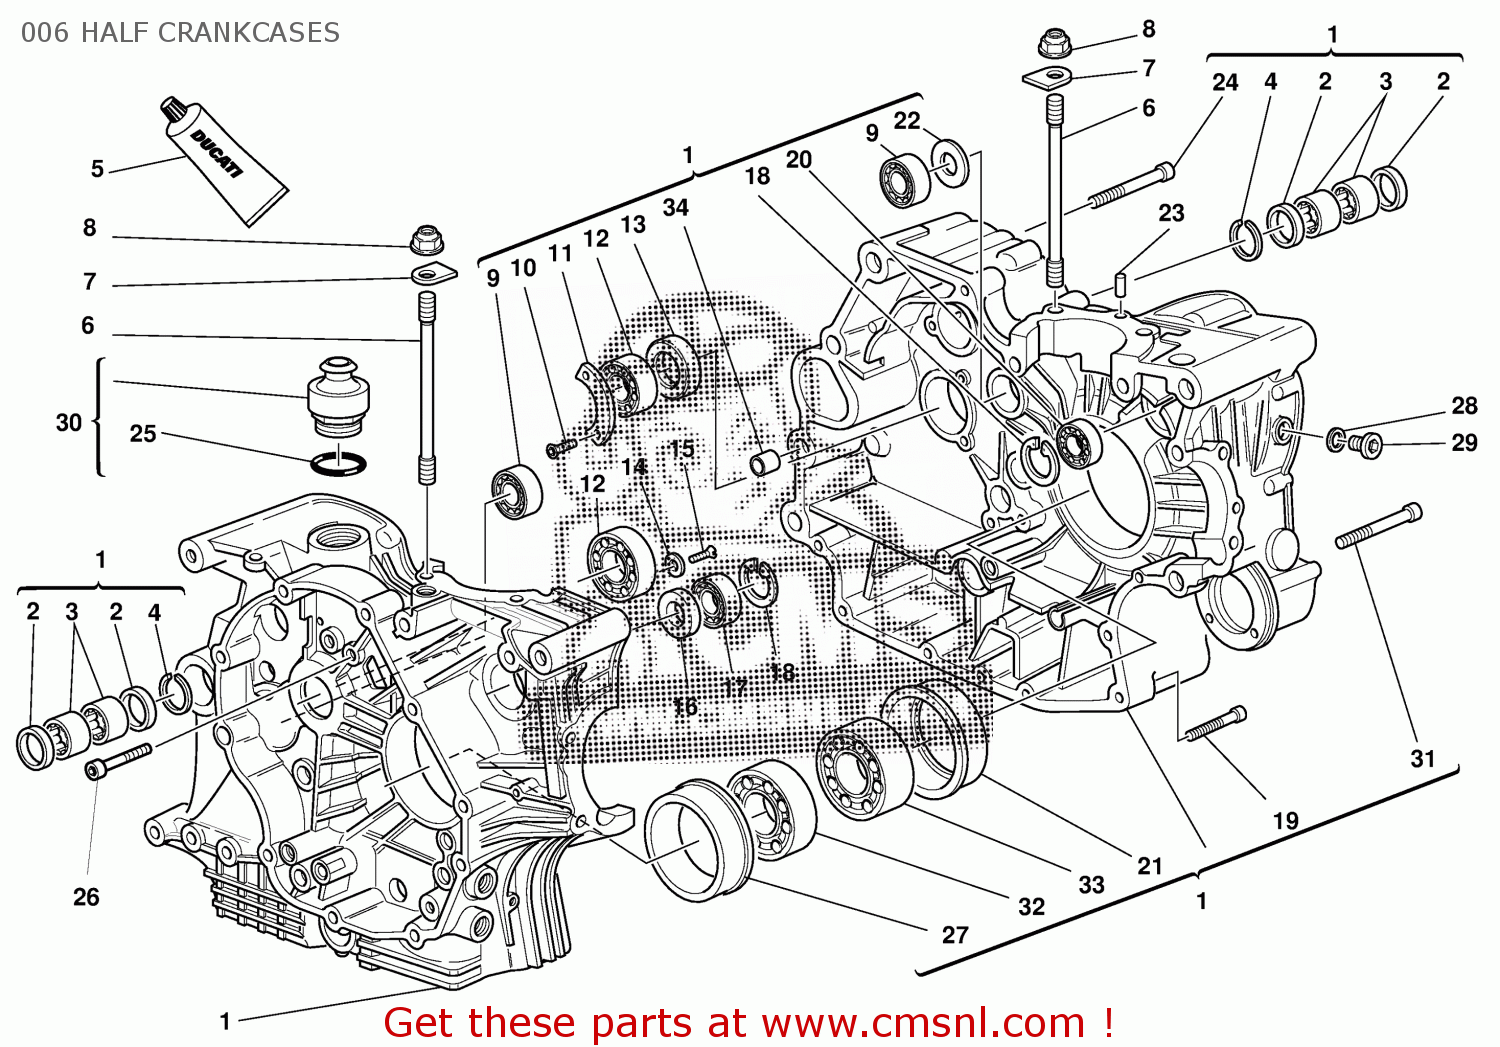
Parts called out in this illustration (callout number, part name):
1	CRANKCASE
2	OIL SEAL
3	BEARING, NEEDLE
4	SPRING RING
5	LIQUID GASKET
6	STUD BOLT FASTENING HEAD CYLINDER
7	WASHER, SPECIAL
8	NUT, FLANGED M10
9	ROLLERS BEARING NJ203ECP
10	SCREW TSPEI M6X12
11	PLATE, RETAINER
12	BEARING 25X62X17
13	OIL SEAL
14	SPACER
15	SCREW TE M6X1.00X16
16	OIL SEAL
17	BEARING
18	CIRCLIP
19	SCREW
20	BALL BEARING 6003 TN9 C3
21	BUSHING
22	WASHER
23	PIN DOWEL
24	SCREW
25	O RING 39.34X2.62
26	SCREW, SPECIAL
27	BUSHING
28	ALUMINIUM GASKET
29	SPECIAL SCREW M12X1
30	VALVE, BREATHER
31	SCREW M6X75
32	BALL BEARING 35BN03D06
33	BEARING
34	PIN DOWEL
